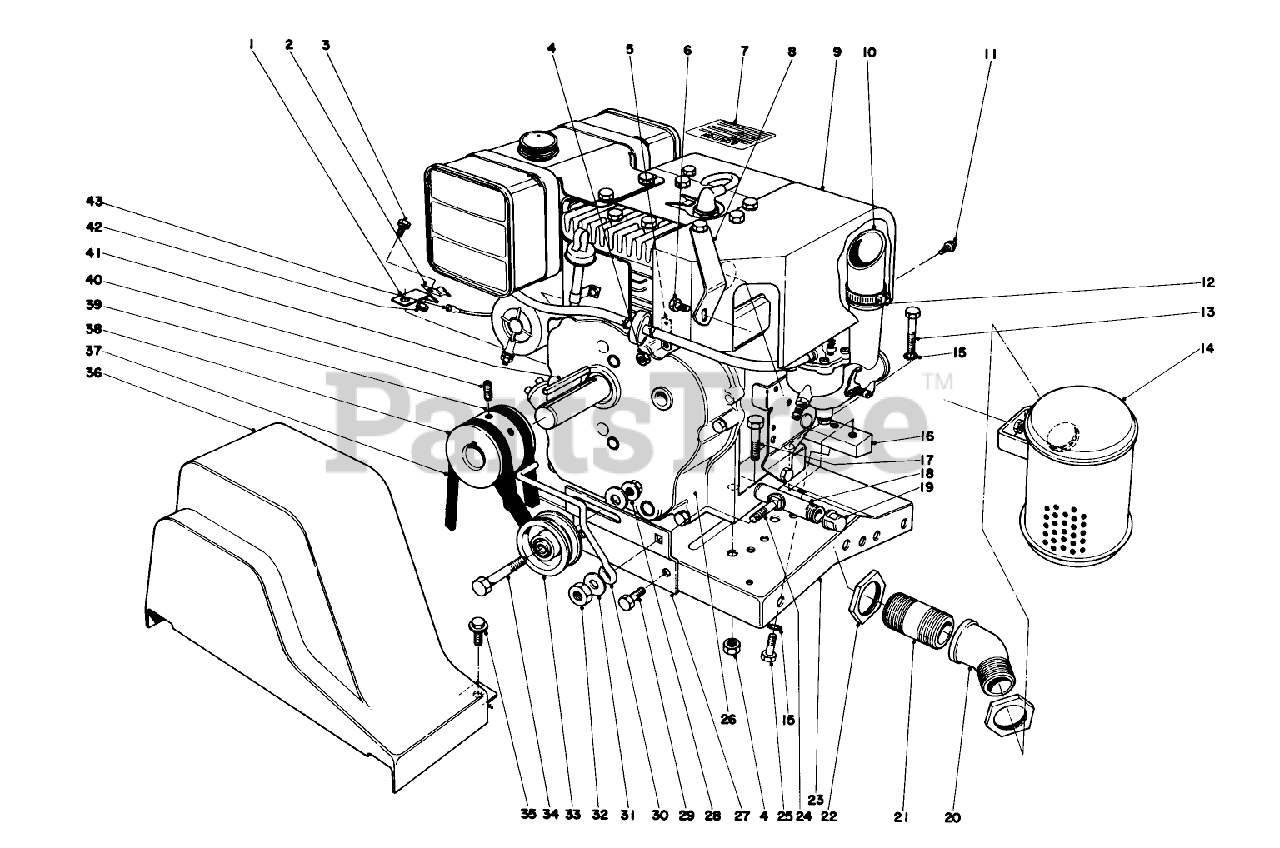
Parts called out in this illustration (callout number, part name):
3	SCREW-HWH
4	NUT-LOCK, CONE
7	Decal Instruction
11	SCREW-HWHTF
13	SCREW-HH
15	WASHER-LOCK
17	SCREW-HH
18	NIPPLE-PIPE
19	Pipe Cap
24	SCREW-CARR
25	SCREW-HH
26	Engine
28	NUT-HHF, WHIZ
29	SCREW-HH, TAP
30	BELT GUIDE
31	WASHER-FLAT
34	SCREW-HH
35	SCREW-HWH
39	V-BELT
42	NUT-KEPS
